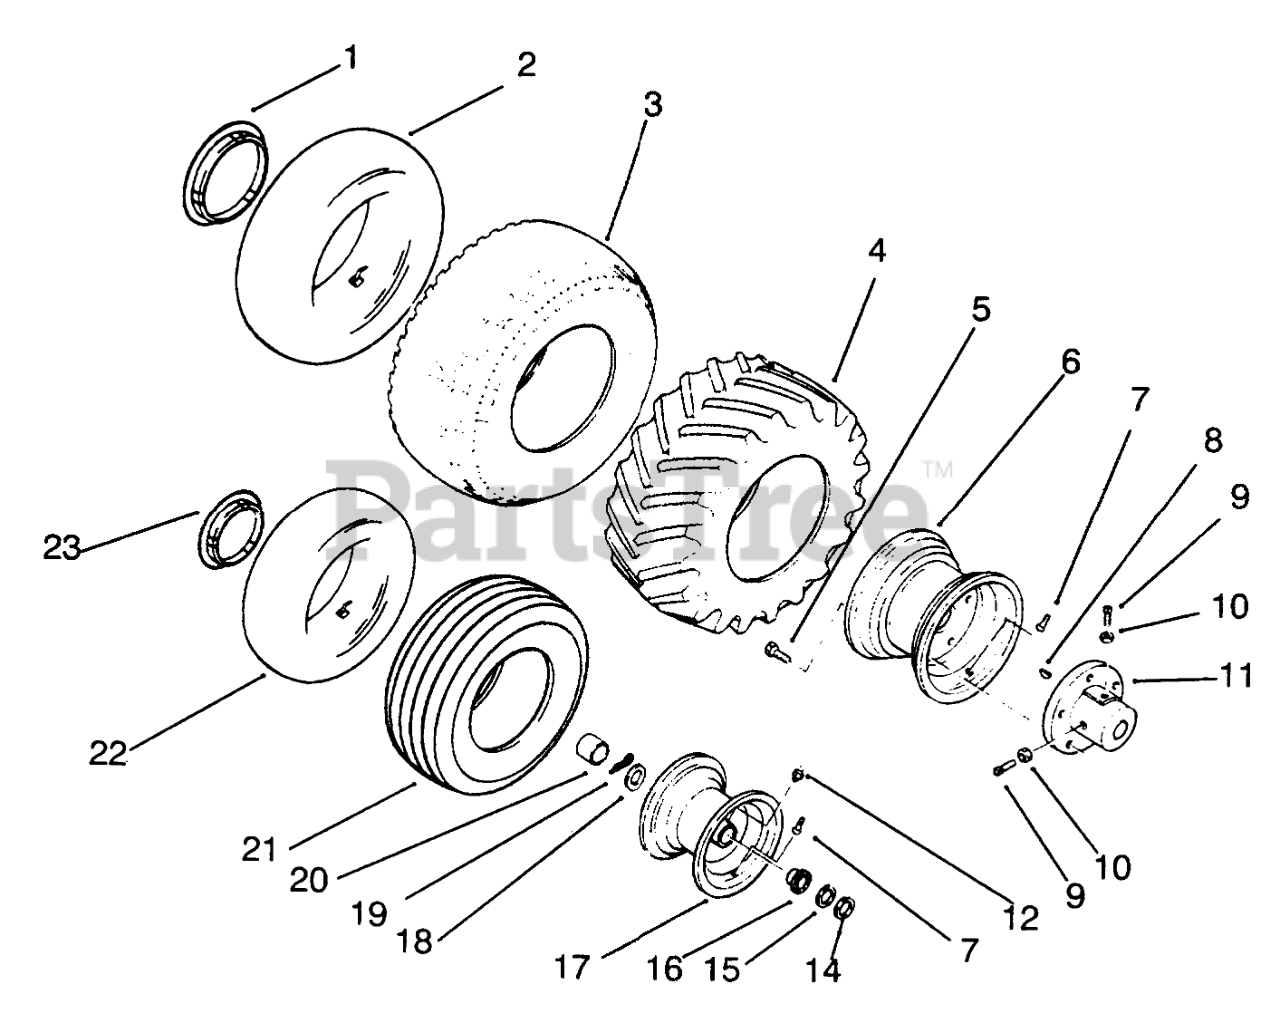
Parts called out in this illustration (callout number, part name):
1	12"-HUB CAP LOGO
2	TUBE-INNER
3	TIRE
4	Tire-Cleat, Rear
5	BOLT-LUG
6	WHEEL
7	VALVE
8	KEY-WOODRUFF
9	SCREW-SET, SQH
10	NUT-JAM
11	Hub Rear
12	ZERK-GREASE
14	WASHER-SHIM
15	WASHER
16	BEARING-WHEEL
17	Wheel Assembly-Front (Incl. Ref.# 7,12, & 16)
18	WASHER WHEEL
19	PIN-COTTER
20	HUBCAP
21	Tire (16 x 6.5-8) 2-Ply -2 Wheel Axel
23	8"-HUB CAP LOGO
